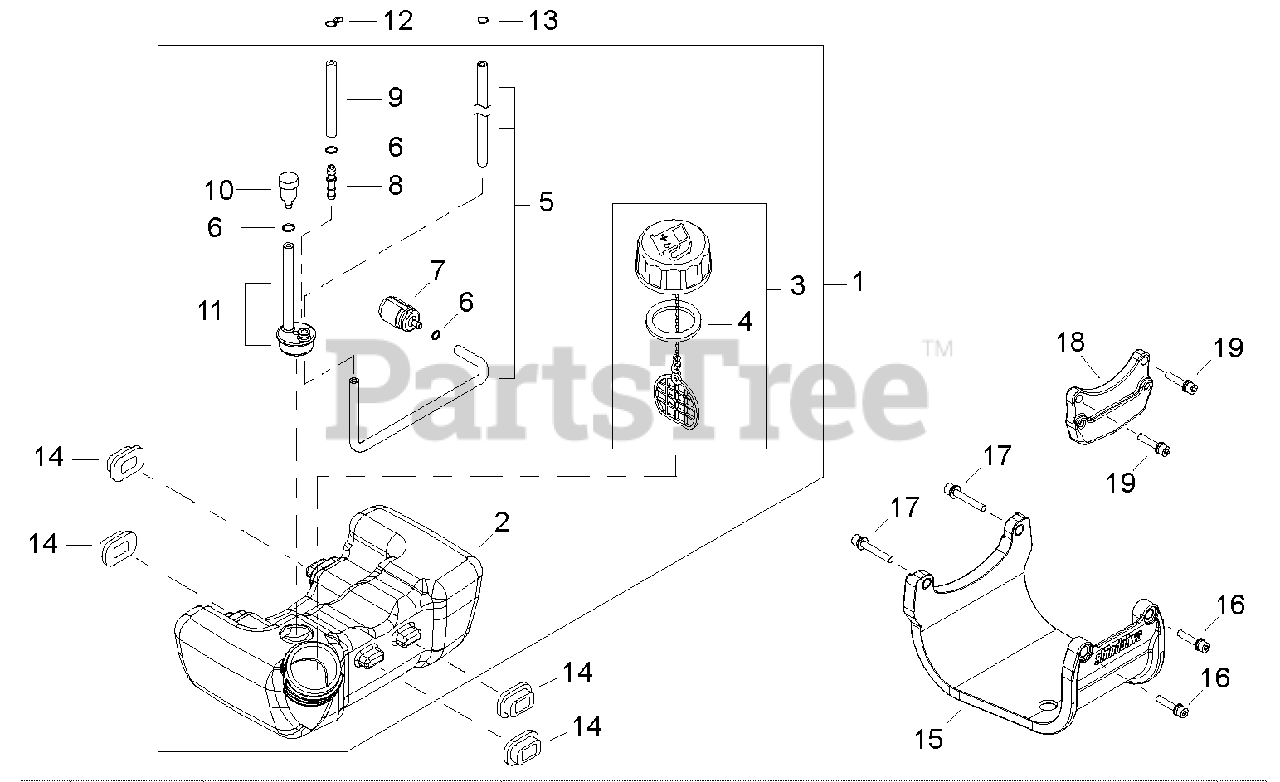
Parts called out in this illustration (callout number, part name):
1	TANK ASSY, FUEL
2	TANK, FUEL
3	CAP ASSY, FUEL
4	GASKET, FUEL CAP
5	PIPE, FUEL 3.3×6×215
6	CLIP Ø6
7	FILTER, FUEL
8	CONNECTOR, PIPE
9	PIPE, FUEL RETURN
10	VENT ASSY
11	GROMMET, FUEL W/VENT PIPE
12	CLIP, SPRING Ø5.2
13	CLIP Ø6
14	CUSHION, FUEL TANK
15	GUARD, PLASTIC FUEL TANK
16	BOLT M5×20
17	BOLT M5×40
18	BRACKET, METAL FUEL TANK
19	BOLT, ADHESIVE M5×20
